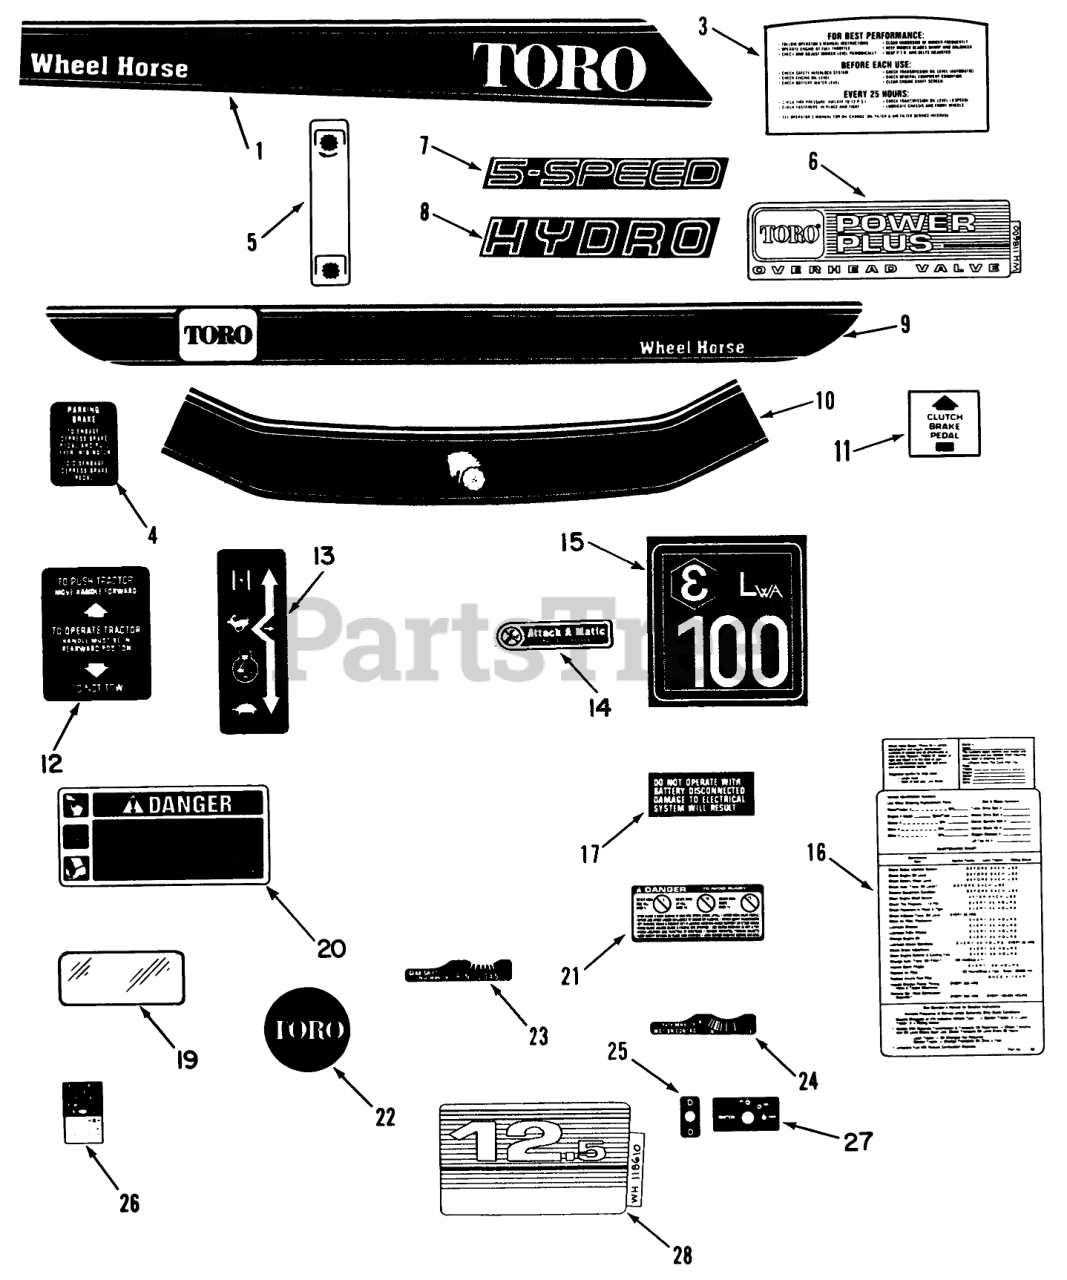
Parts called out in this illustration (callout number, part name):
1	DECAL-HOOD 212-5 R H
3	Decal-Hood Rear
4	DECAL PARKING BRAKE
5	DECAL-PTO
6	DECAL-PWR PLUS
7	DECAL-MODEL 5-SPEED
8	DECAL-MODEL HYDRO
9	DECAL-FENDER
10	DECAL-FRONT HOOD
11	DECAL CLUTCH & BRAKE
12	DECAL-PUSH
13	DECAL-THROTTLE
14	Decal-Attach-A-Matic
15	DECAL-EUROPE
16	MAINTENANCE-DECAL
17	DECAL ELECT SYSTEM
19	DECAL-OVERLAY
20	DECAL-DANGER
21	DECAL-DANGER
22	DECAL-TORO ENGINE
23	DECAL-SHIFT 5-SPEED
24	DECAL-MOTION CONTROL
25	DECAL-LIGHTS
26	DECAL-PTO BELT ADJ
27	DECAL-IGNITION
28	DECAL-PWR PLUS 12.5
